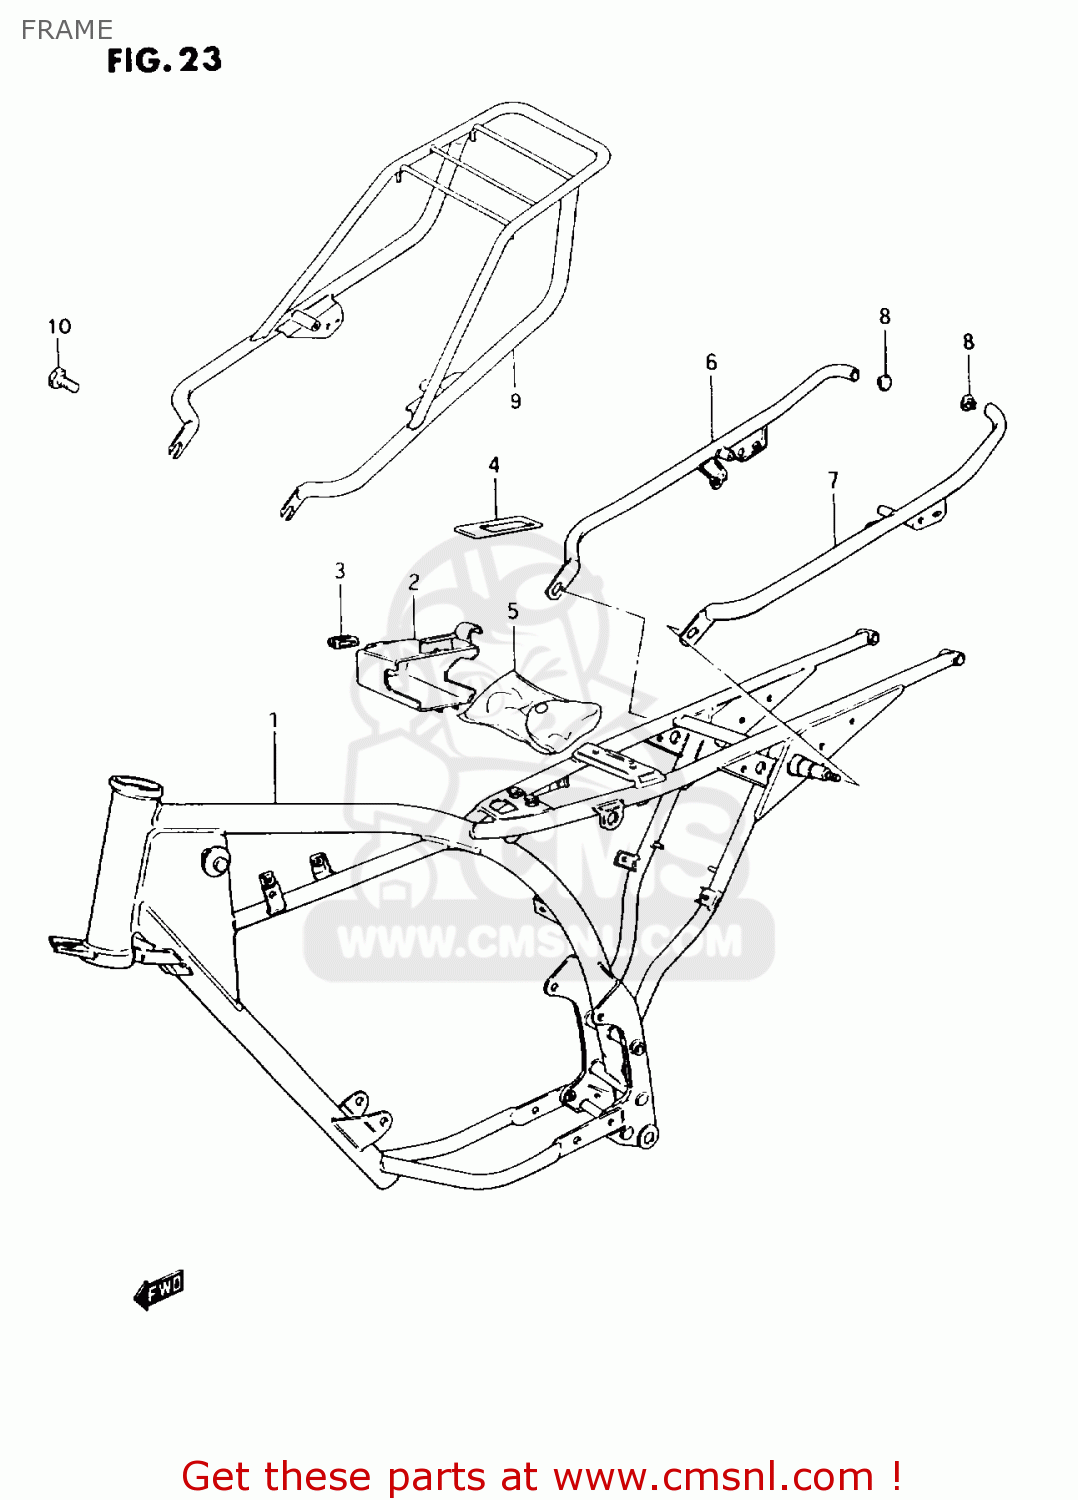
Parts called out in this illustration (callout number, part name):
1	FRAME (BLACK)
2	HOLDER,TOOL
3	CUSHION
4	BAND,TOOL
5	TOOL ASSY
6	GRIP, FRAME HANDLE RH
7	GRIP, FRAME HANDLE LH
8	CAP(OD:17)
9	CARRIER
10	BOLT
